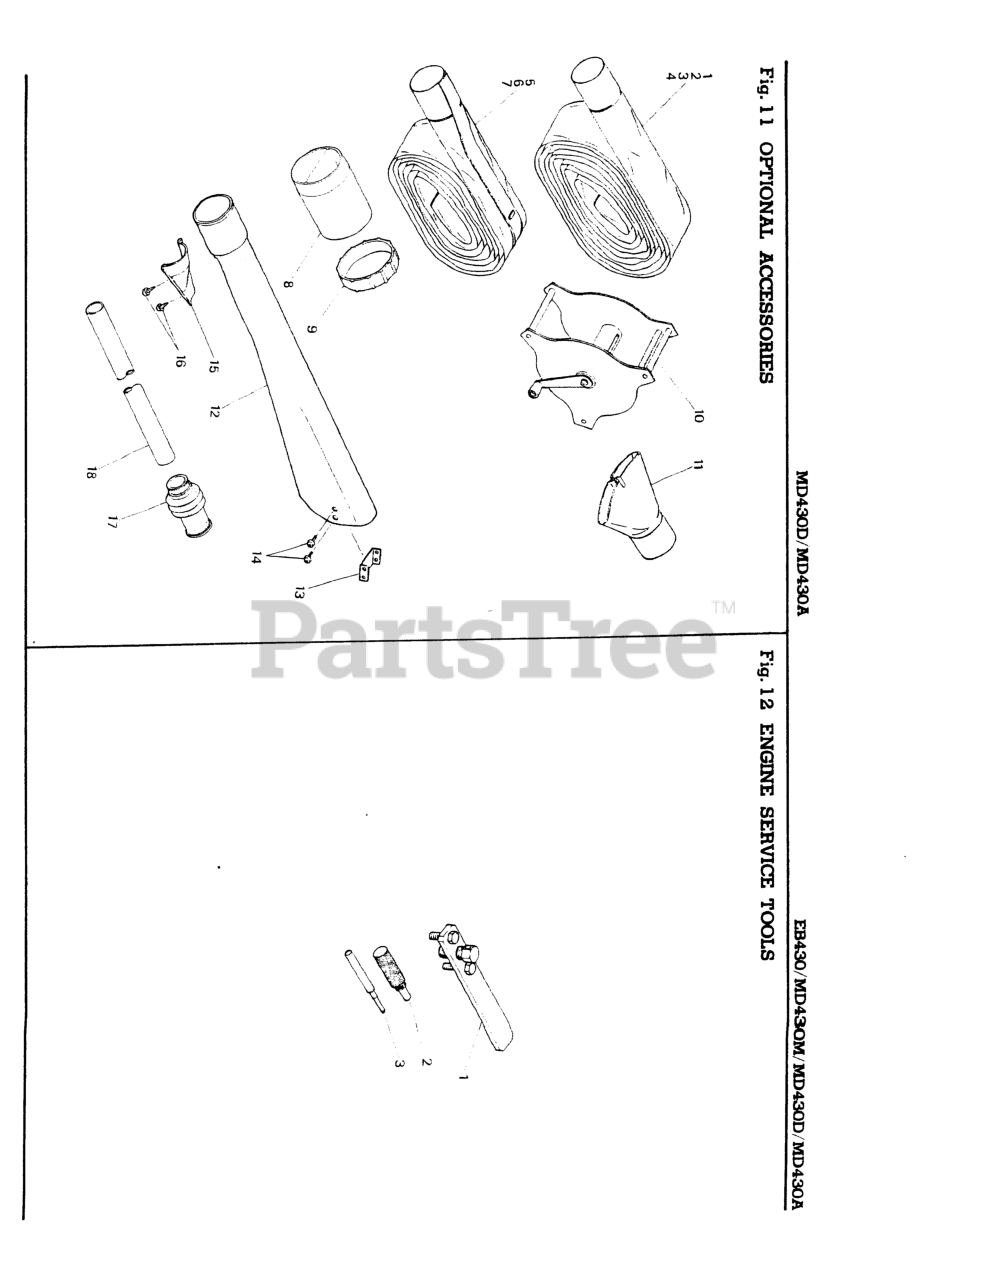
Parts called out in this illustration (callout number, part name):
1	PULLER ASSEMBLY (TOOL)
2	STOPPER (TOOL) (RPLS 3320-9641
3	GUIDE (TOOL)
